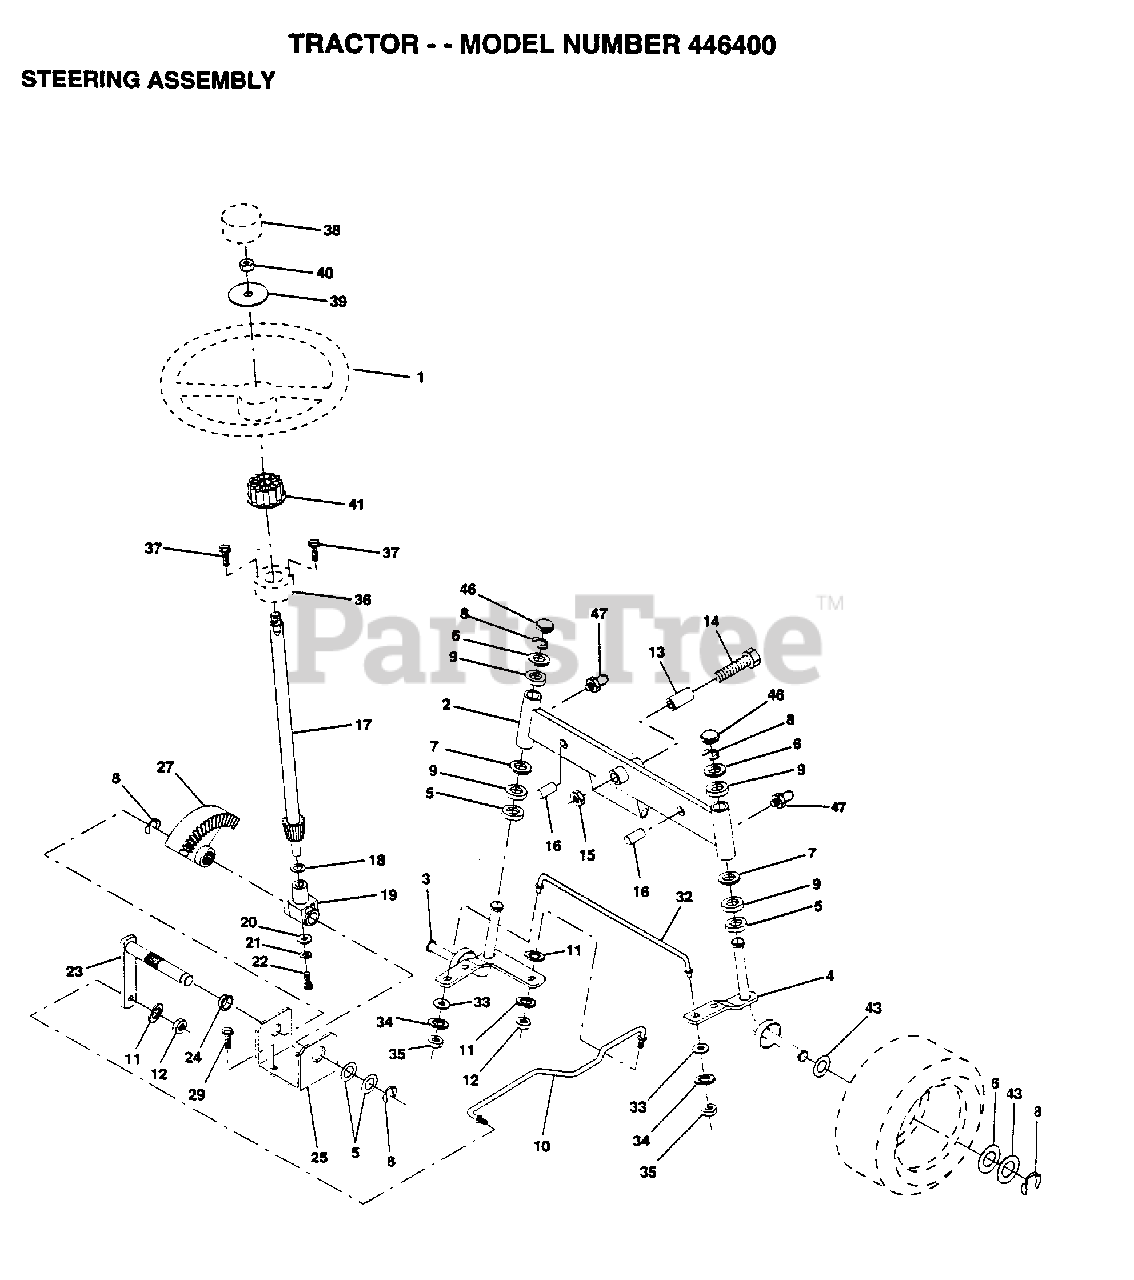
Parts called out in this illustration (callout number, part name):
2	AXLE ASM FRONT
3	SPINDLE LH
4	SPINDLE RH
5	WASHER .T
6	WASHER
7	WASHER
8	RING
9	COL. SRTG. BEAR.
11	LOCKWASHER
13	BEARING
14	BOLT HEX 5/8-11
15	"NUT-LOC,FLANGE LT"
16	AXLE PIN
18	THRUST WASHER
19	SUPPORT.SHAFT
21	LOCKWASHER
22	"SCREW,SPECIAL"
24	NYLINER T
25	"BRKT,STEERING"
27	GEAR SECTOR
29	SCREW
32	TIE ROD
33	WASHER M
34	LOCKWASHER
35	NUT.LOCK.5/16-24
36	BUSHING.STRG.3/4
37	SCREW.10-24X1/2
38	INSERT STEERING
39	WASHER
41	ADAPTER LT
43	WASHER
46	CAP
47	ZERK M
